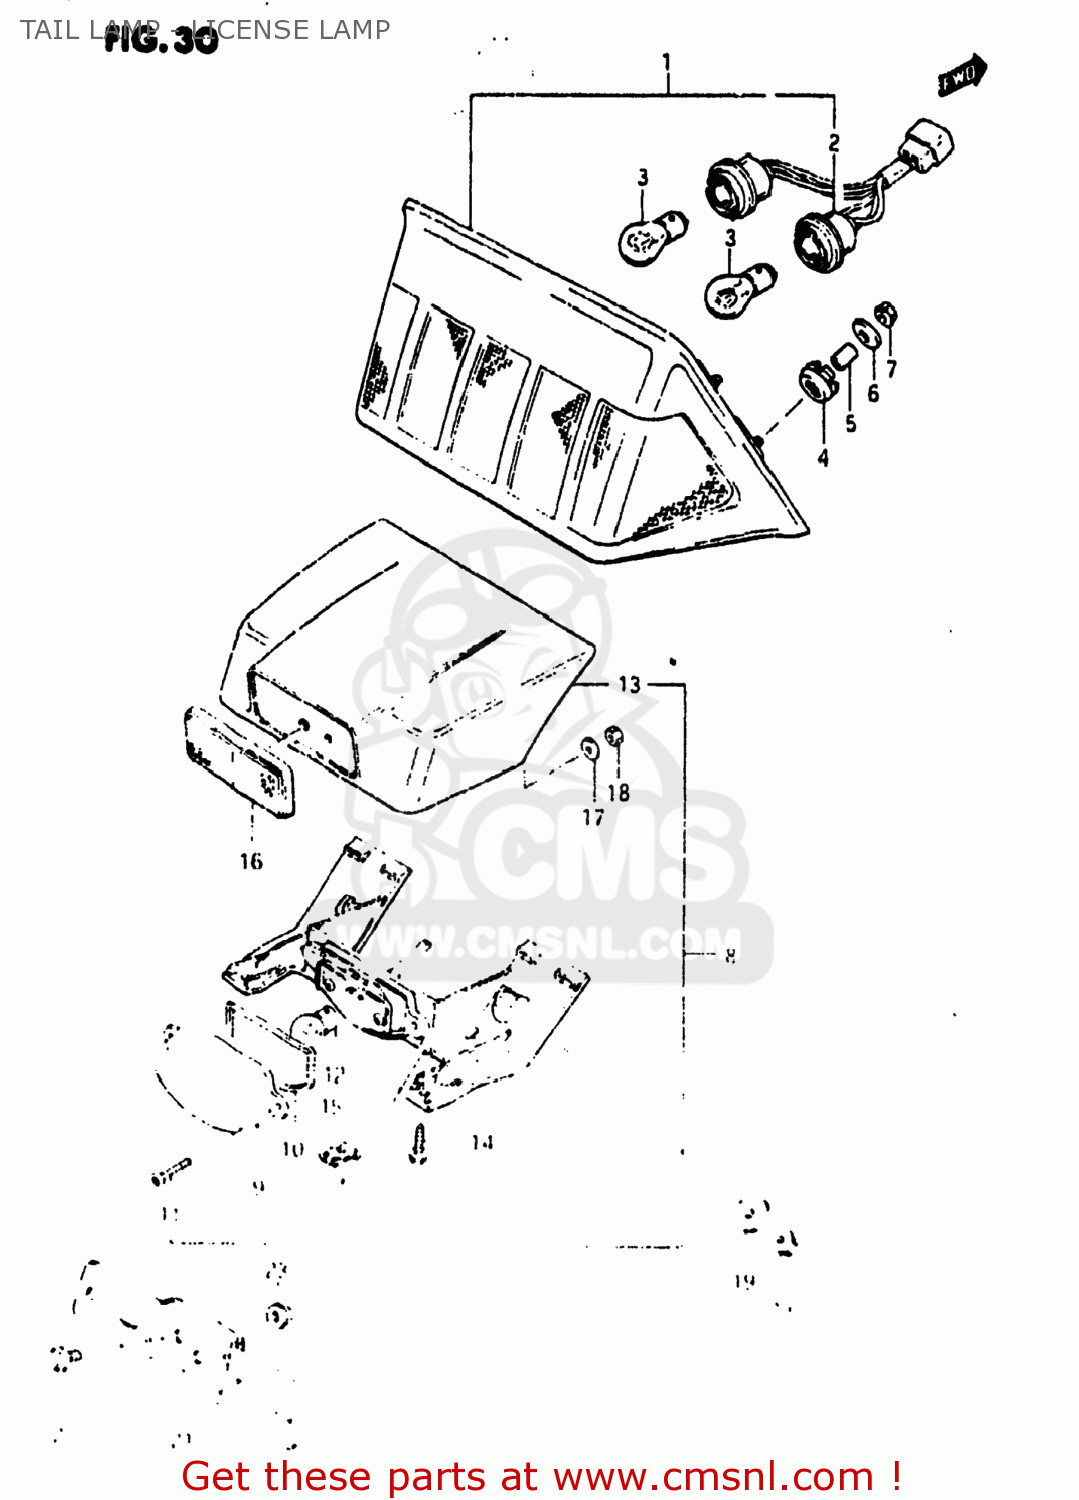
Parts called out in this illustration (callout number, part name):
1	LAMP ASSEMBLY,REAR COMBINATION
2	SOCKET,REAR COMBINATION LAMP
3	BULB(12V23/8W,TOKAI DENSO)
4	CUSHION
5	SPACER (6.4X9X13.5)
6	WASHER
7	NUT
8	LAMP ASSEMBLY,LICENSE
9	LENS,LICENSE LAMP
10	GASKET,LICESE LAMP (NAS)
11	SCREW
12	BULB
13	COVER,LICENSE LAMP
14	SCREW
15	COVER,TURN,RIGHT
16	REFLEX REFLECTOR,REAR
17	WASHER(5.2X16X1)
18	NUT
19	WASHER
20	NUT
21	BRACKET,LICENSE PLATE
22	BOLT
23	NUT
